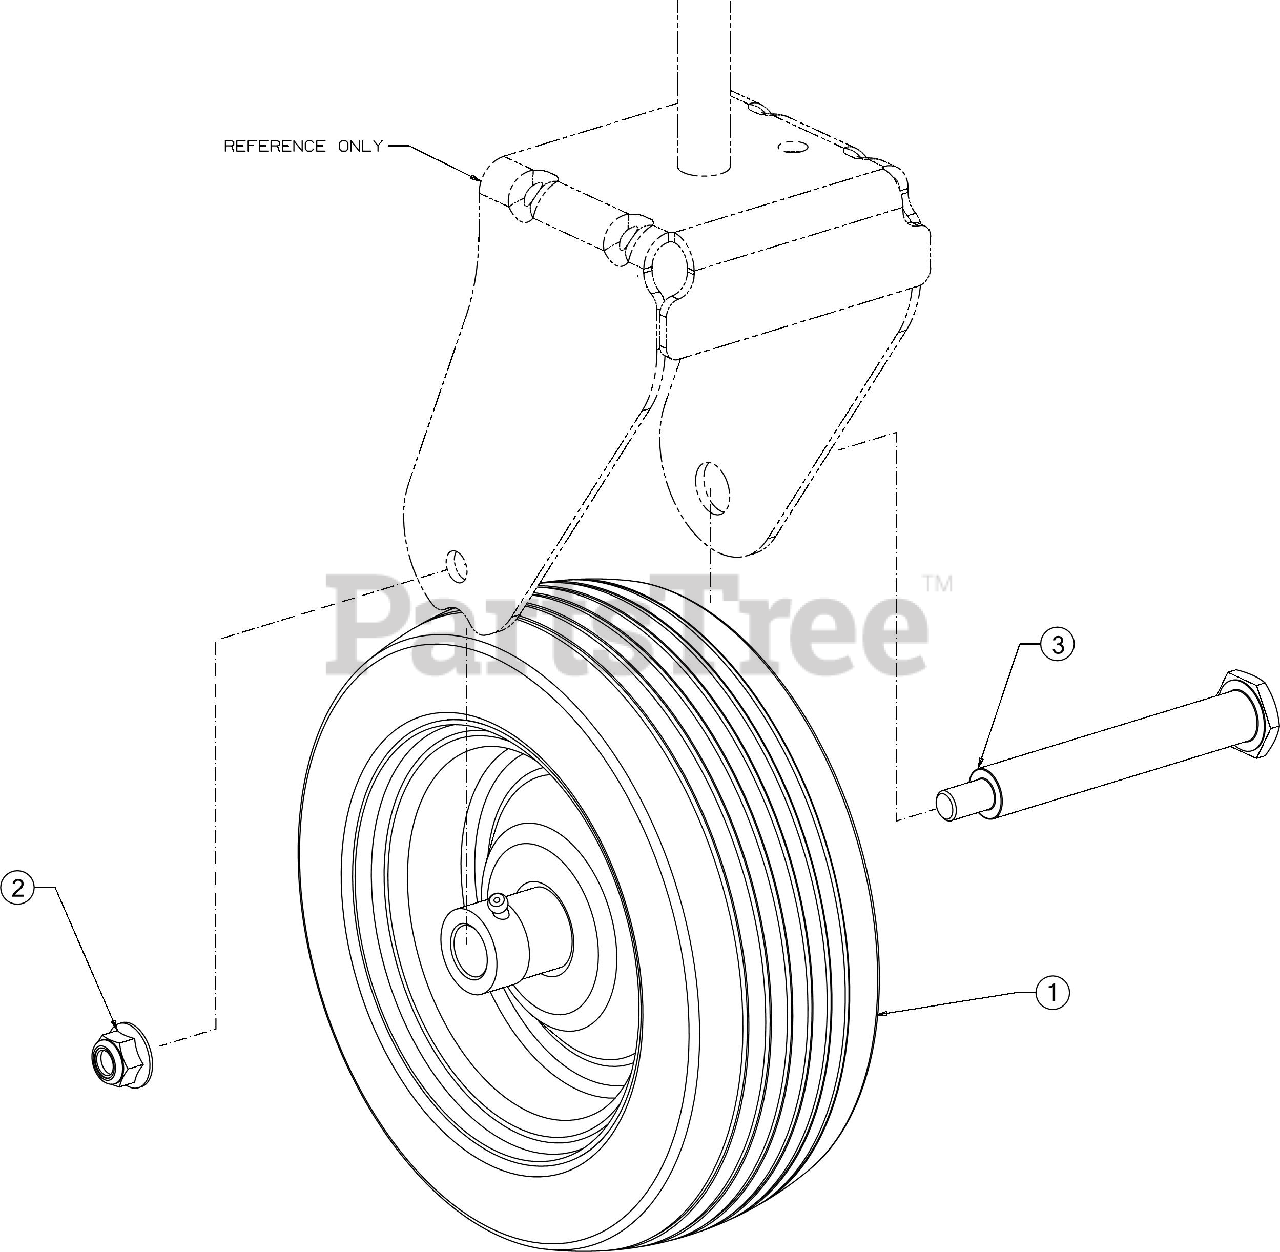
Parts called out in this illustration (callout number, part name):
1	WHEEL ASSEMBLY (8 x 3)
1	FLANGE BUSHING
3	SHOULDER SCREW .625 x 3.94
